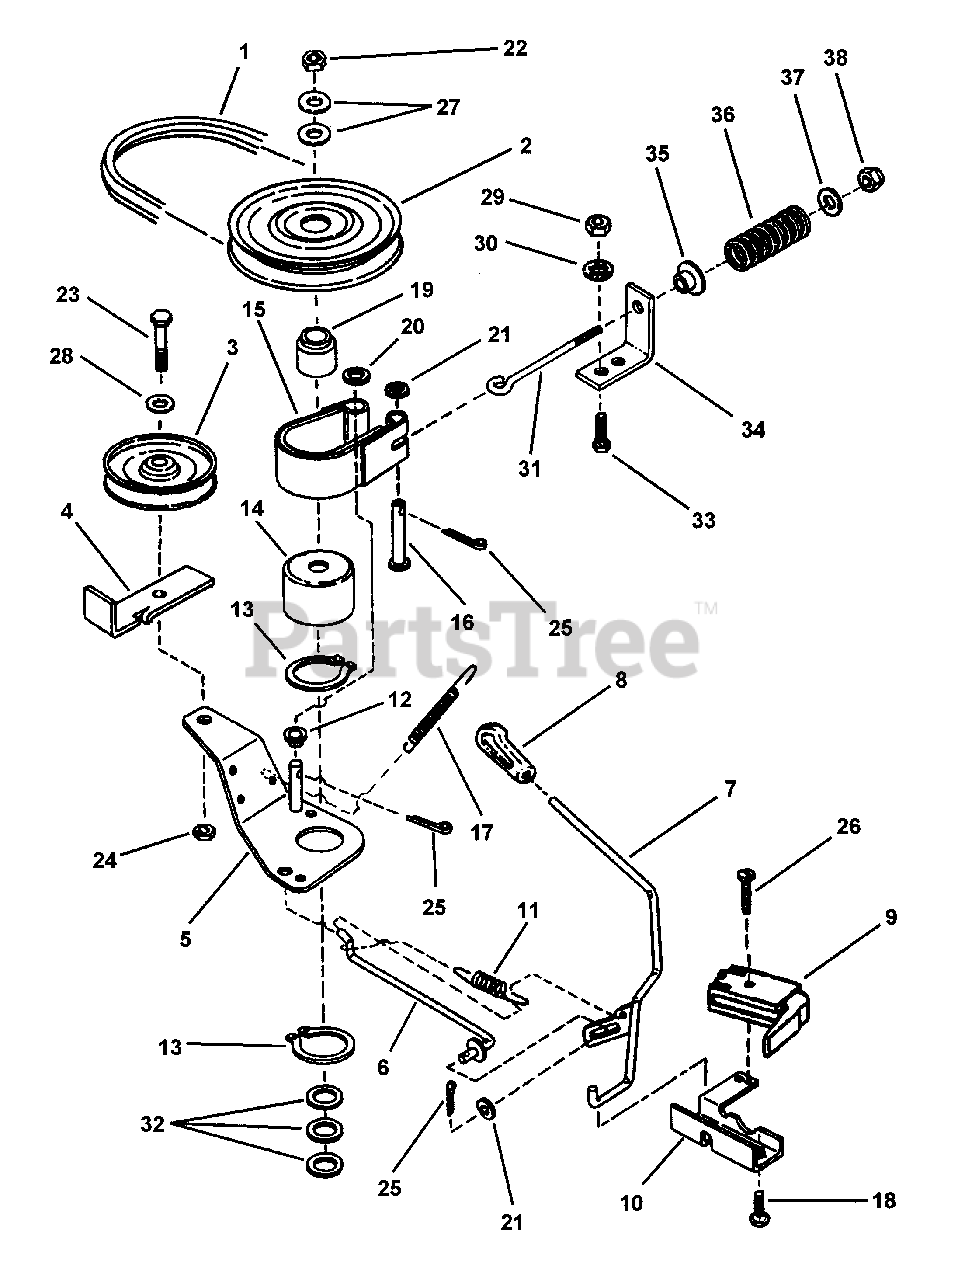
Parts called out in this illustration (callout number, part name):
1	BELT, Drive
2	PULLEY, Spindle
3	PULLEY, Idler (4" O.D, 375" I.D.)
4	RESTRICTOR, Belt
5	WELDMENT, Idler Arm
6	ROD, Idler
7	HANDLE, Blade Lever (On-Off)
8	GRIP, Handle
9	SWITCH, Deck Interlock
10	MOUNT, Blade Lever and Switch
11	SPRING, Blade Handle
12	SPACER
13	RING, 2" External Retaining
14	DRUM, Brake
15	BAND, Brake
16	PIN, 1/4 x 1-5/8" Clevis
17	SPRING
18	SCREW, 1/4-20 x 5/8" Hex Washer Self-Tap
19	HUB, Pulley
20	WASHER, 3/8" Flat
21	WASHER, 1/4" Flat
22	NUT, 3/4-16 Hex Jam
23	SCREW, 3/8-16 x 1-1/2" Hex Head Cap, Grade 5
24	NUT, 3/8-16 Hex Nyloc
25	PIN, 3/32 x 3/4" Cotter
26	SCREW, #10-32 x 1" Hex Washer Self-Tap
27	WASHER, 49/64 x 1-1/2" Flat
28	WASHER, 3/8" Flat
29	NUT, 5/16-24 Hex
30	WASHER, 5/16" Lock
31	EYEBOLT, 1/4-20 x 4"
32	WASHER, 3/4" Flat
33	SCREW, 5/16-24 X 3/4" Hex Head Cap, Grade 5
34	ANCHOR
35	BUSHING
36	SPRING
37	WASHER, 9/32" Flat
38	NUT, 1/4-20 Hex Top Lock
